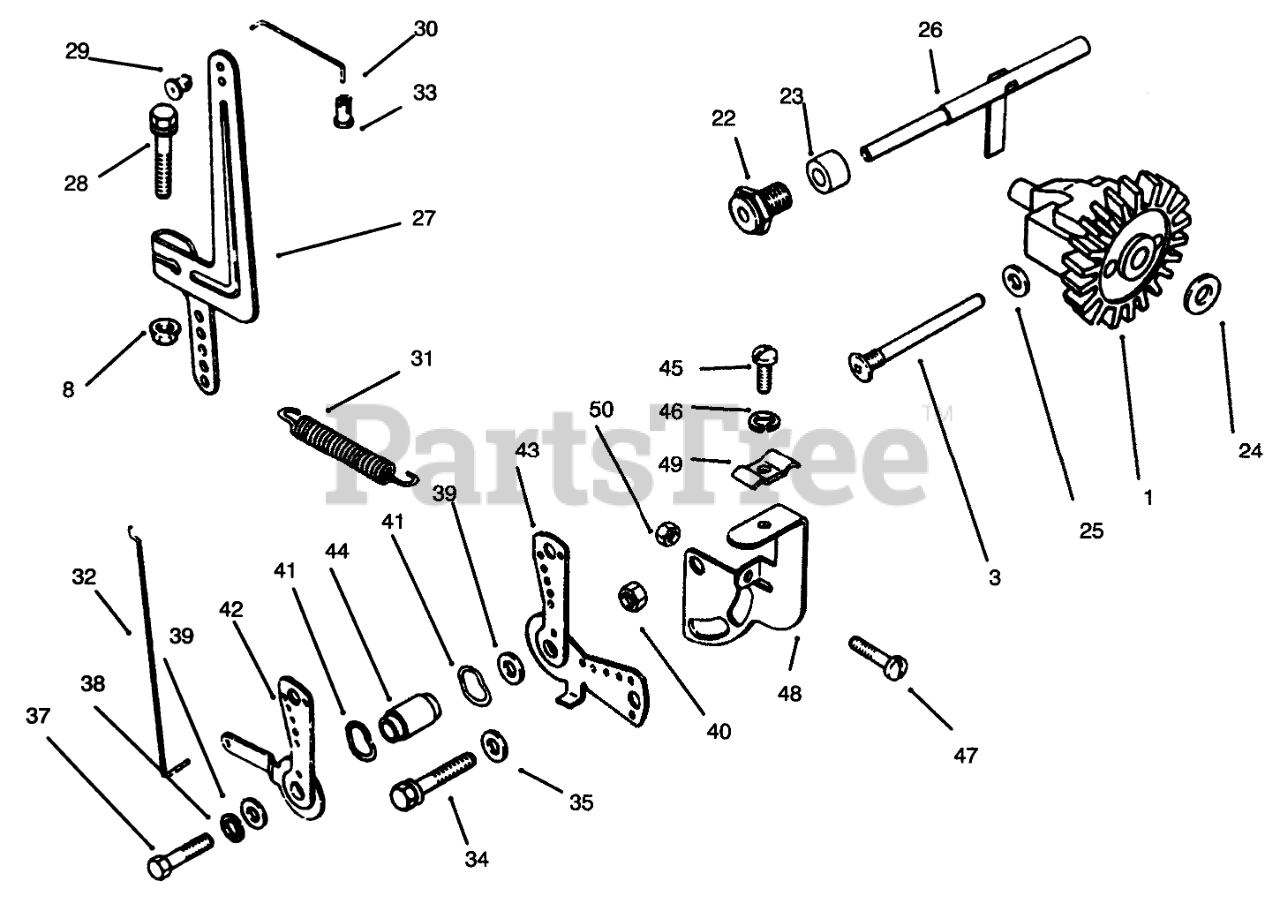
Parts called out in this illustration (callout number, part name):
1	Kit, Governor Gear
3	Pin-GovemorStop
8	Palnut
22	Bushing
23	Spacer
24	Washer
25	Washer
26	Kit-Governor Cross Shaft
26	Kit-Governor Shaft
27	Lever-Governor
28	Screw
29	Bushing
30	Linkage
31	Spring
32	Linkage-Choke
33	Bushing
34	Screw
35	Washer
37	Screw
38	Washer
39	Washer
40	Nut
41	Washer
42	Lever-Choke Control
43	Lever-Throttle Control
44	Spacer
45	Screw
46	Washer
47	Screw
48	Bracket-Clutch Contro;
49	Clamp
50	Nut
